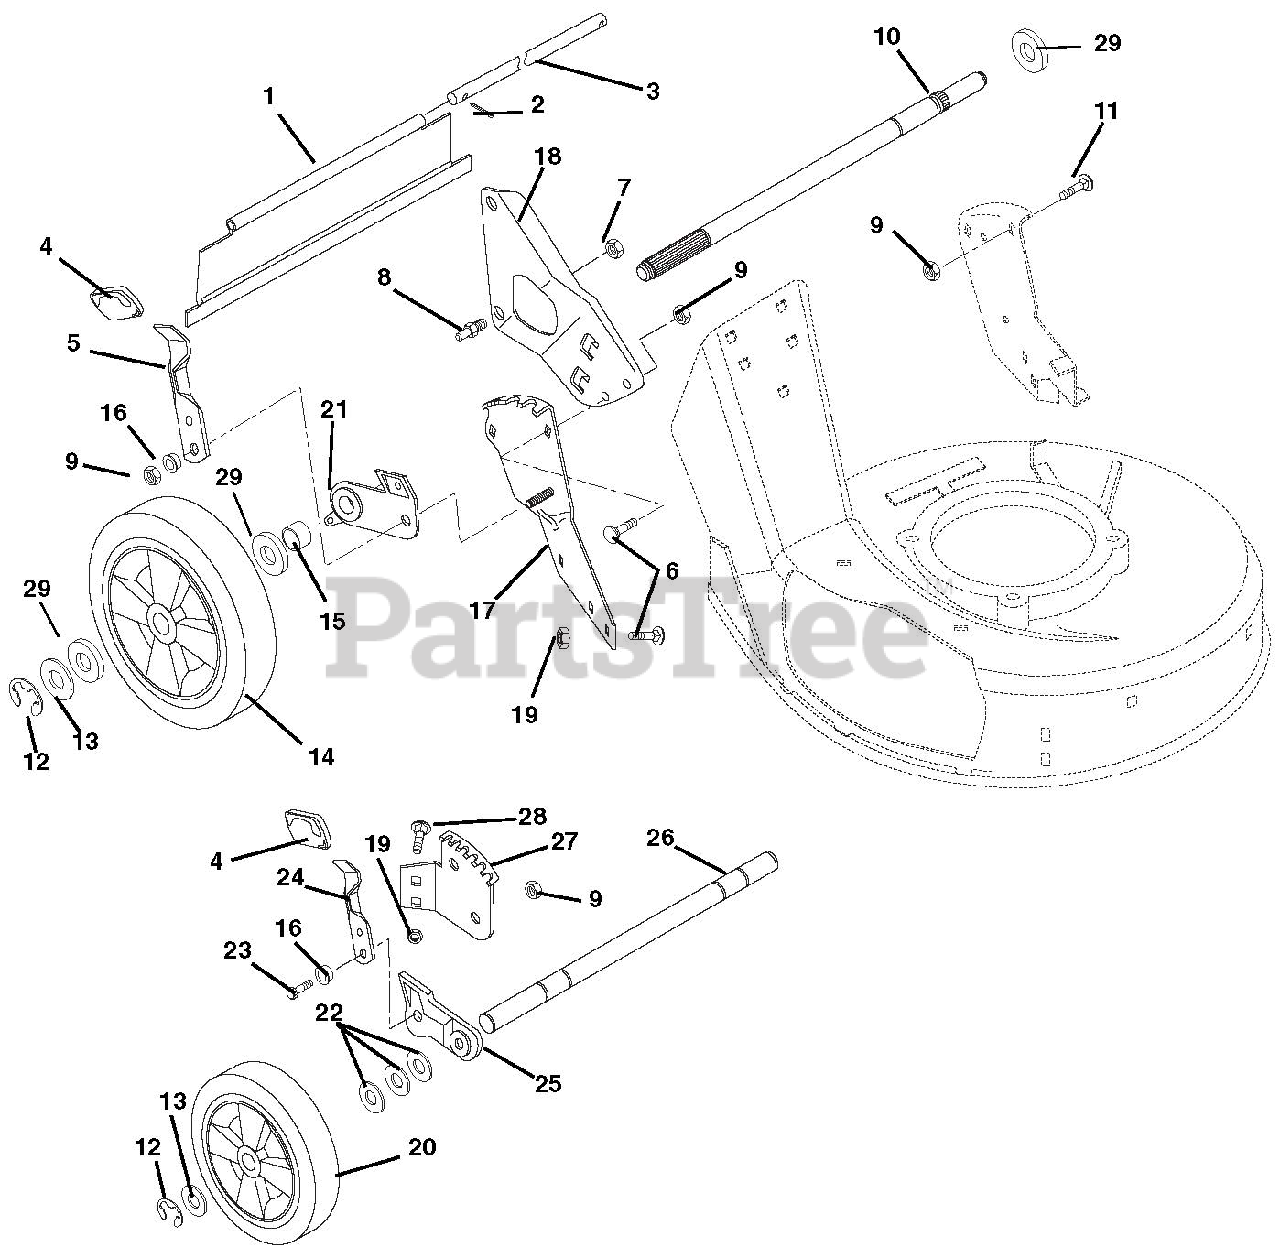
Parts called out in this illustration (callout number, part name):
1	REAR PROTECTIVE GUARD, S.P.
1	REAR PROTECTIVE GUARD, PUSH
2	@PIN-CTR .06X.50 EXTPRSQCT YWZ
3	ROD
5	LEVER, HEIGHT ADJUSTMENT
6	@BLT-RHDSSQNK .31-18X.62 G5YZ
7	@NUT-LK-CTR .38-16 YWZC
8	HANDLEBAR STUD
9	@NUT-LK-TOP-FLG .31-18 YWZC
10	REAR AXLE,5/8 DIA
10	REAR AXLE-PUSH MOWER MM
11	BLT-RDHDSQNK .31-18X1.0 SHTYZ
12	RG-RTNG-EXT .500X.042 (E)
13	WSHR-FL-STL .505X.880X.072 YWZ
14	WHL, LH 10.50"
14	KIT, REAR WHEEL REPLCMNT-PUSH
14	WHL, RH 10.50"
14	10 1/2 TIRE SKIN
15	SPACER TUBE, SELF PROPEL
15	SPACER TUBE PUSH RH
16	BSHG-FLG .32X.500X.344X.880
17	QUADRANT, REAR LH
17	QUADRANT, REAR RH
18	RH HANDLEBAR MTG. BRKT
18	LH HANDLEBAR MTG. BRKT
19	@NUT-LK-TOP-FLG .31-18 YWZC
20	WHL 7.50" .50 BORE, 1.50 HUB
21	REAR BRACKET & BEARING ASSY LH
21	REAR BRACKET & BEARING ASSY RH
21	REAR BRACKET & BEARING ASSEMBL
22	WSHR-FL-STL .52X.827X.062 YWZC
23	@BLT-HEX .31-18X1.00 GR5 YWZC
24	FRONT HEIGHT ADJUSTMENT LEVER
25	LEFT ADJUSTOR BRACKET ASSEMBLY
25	RIGHT ADJUSTOR BRACKET ASSEMBL
26	FRONT AXLE
27	FRONT QUADRANT, LH
27	FRONT QUADRANT, RH
28	@BLT-RDHDSQNK .31-18X.50 G5YZ
29	SPACER .531 X 1.00 X .225
